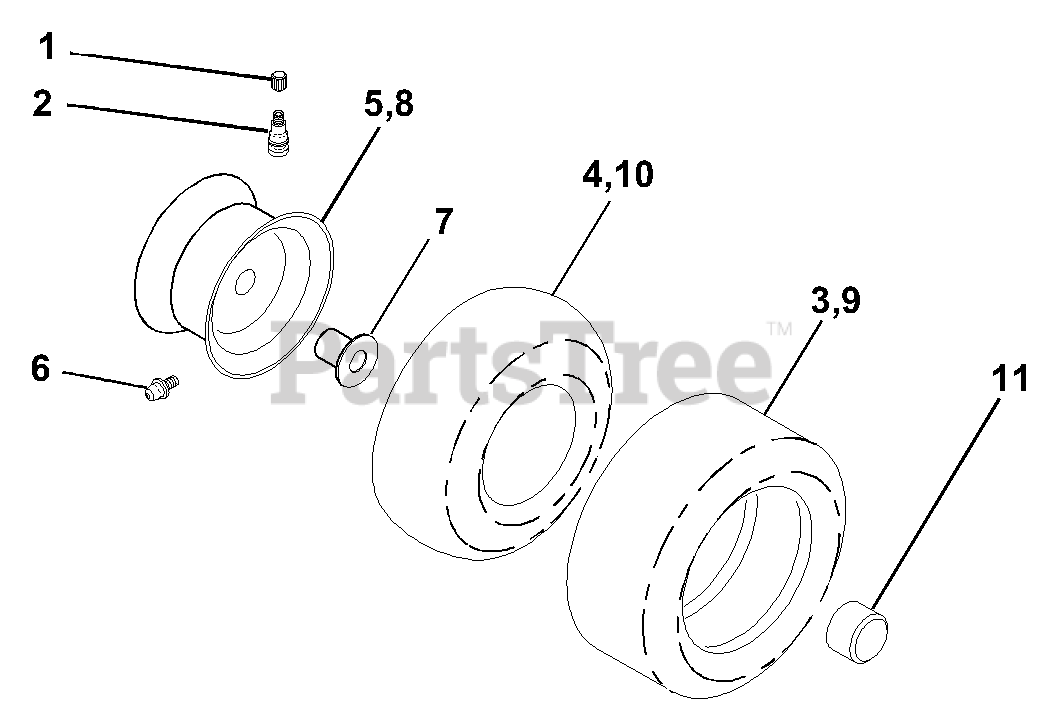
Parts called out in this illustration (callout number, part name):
1	Cap Valve Tire
2	Stem Valve
3	Tire F Ts 15 X 6 0 - 6 Service
4	Tube Front
5	Rim Asm 6"front Service
6	Fitting Grease
7	Bearing Flange
8	Rim Asm 8"rear Service
9	Tire R Ts 20x10-8 C Service
10	Tube Rear
11	Cap Axle Blk 1 50 X 1 00
